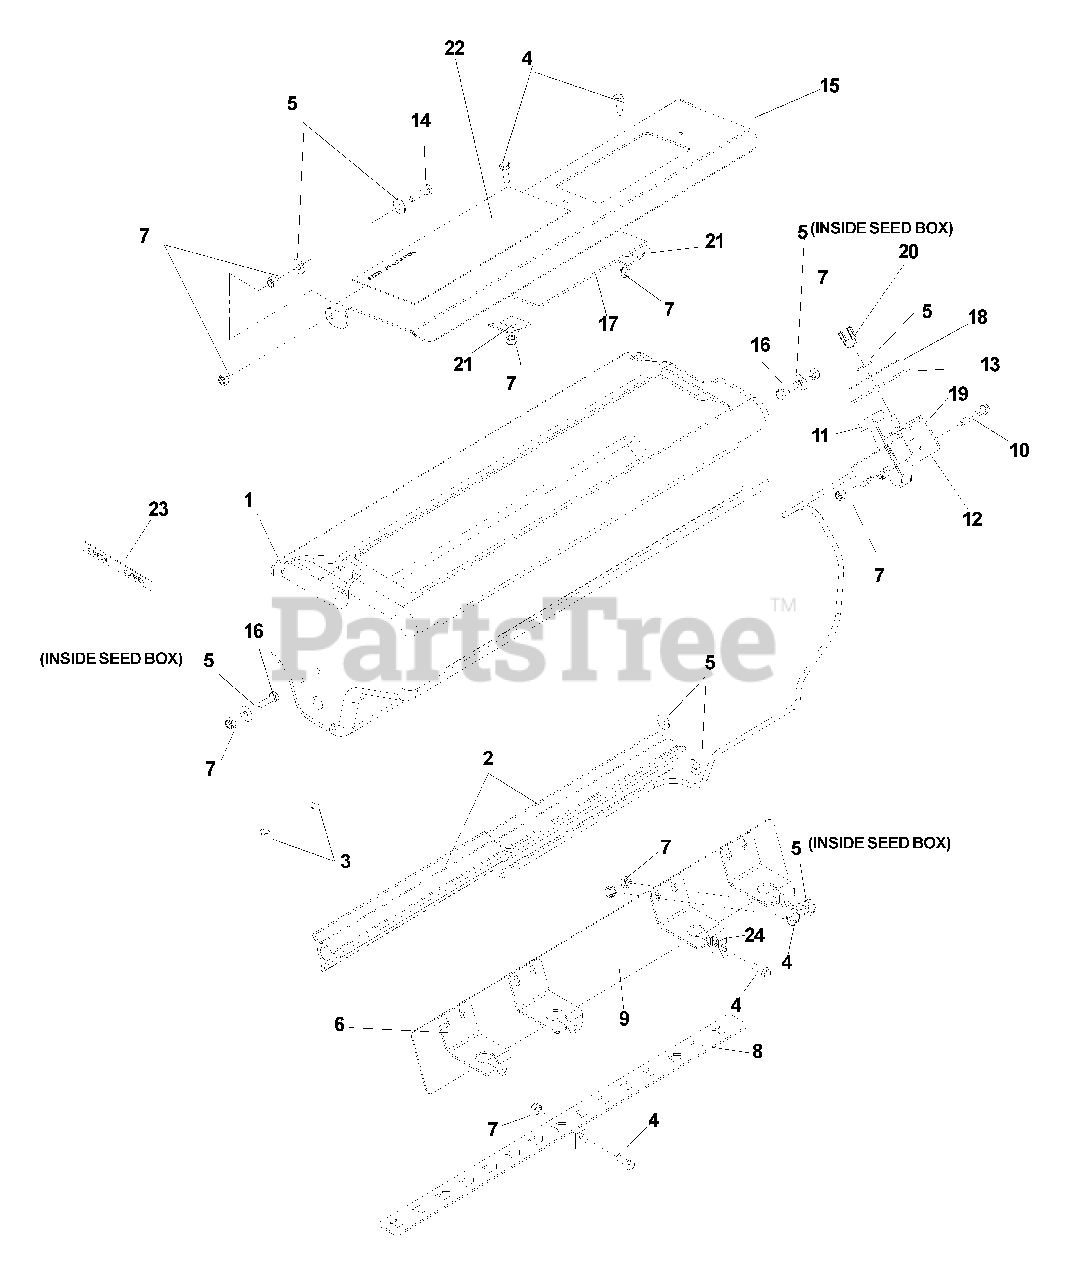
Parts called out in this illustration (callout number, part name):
3	SCREW, #8-32 X 3/8, TAPPING
4	HCS 1/4C X 3/4
5	WASHER, 1/4, FLAT
7	NUT, 1/4C, NYLOC
10	HCS 1/4C X 1 1/2
11	SEEDER CABLE
14	HCS 1/4C X 1
16	HCS 1/4C X 1
17	SEED WINDOW
18	DECAL, SEED DIAL
19	RHSNB 1/4C X 3/4
20	WINGNUT, 1/4C, NYLOC
21	WINDOW CLIP
22	DECAL, SEED APPICATION
23	DECAL, OPEN/CLOSE
24	CABLE CLAMP
